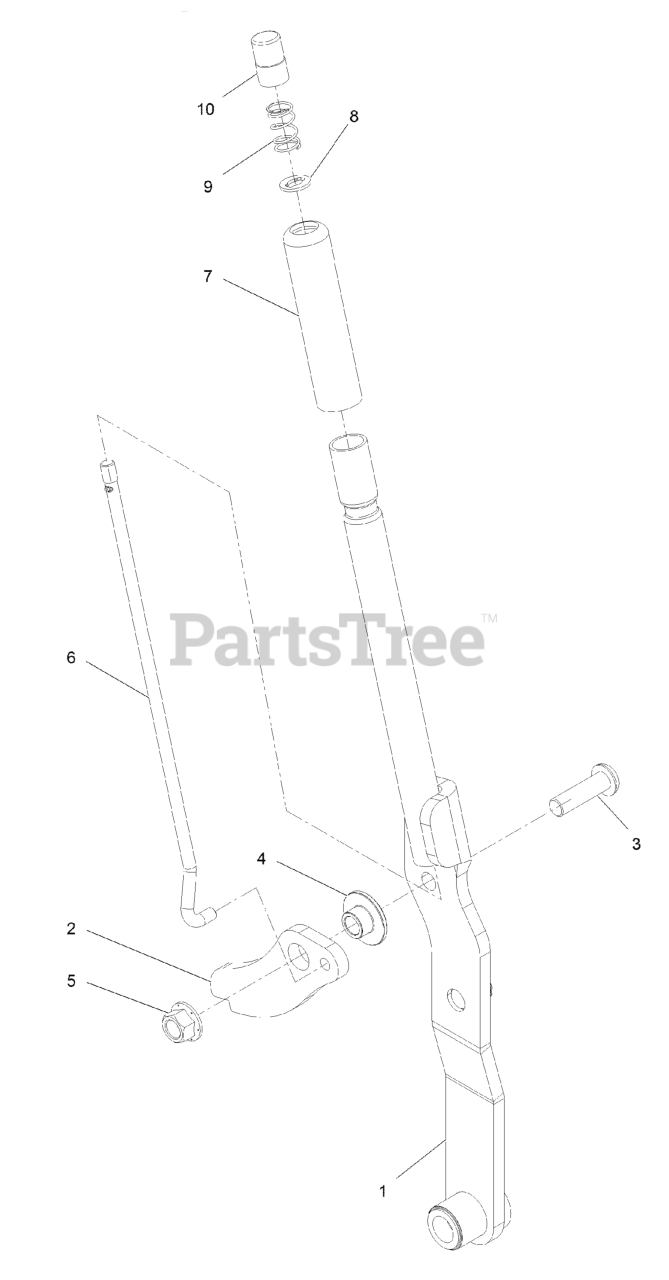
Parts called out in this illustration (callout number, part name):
1	ASM, HOC LEVER W/ BUSHINGS
2	ARM, TRANSPORT LOCK
3	SCREW-HSBH
5	Nut-Lock 1/2-13
6	LINC, HOC
8	WASHER-SPECIAL
9	SPRING-COMPRESSION
